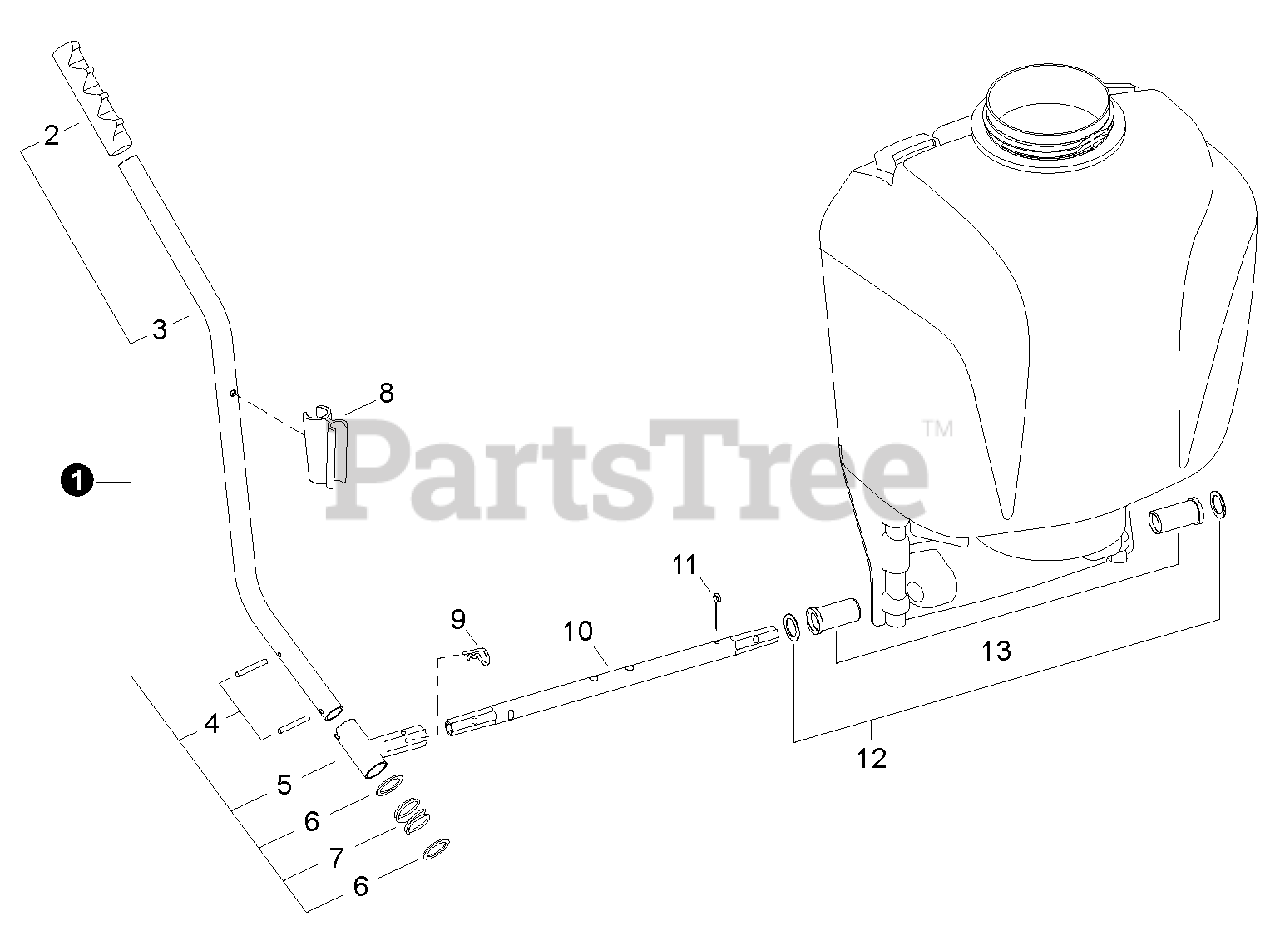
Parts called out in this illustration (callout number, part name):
1	PUMP LEVER KIT
2	GRIP, LEVER
3	LEVER, PUMP
4	PIN, METERING LEVER
5	BRACKET, LEVER
6	WASHER
7	SPRING, METERING LEVER
8	CLIP, WAND
9	PIN, SPLIT
10	SHAFT, PUMP
11	PIN, SHAFT
12	WASHER
13	BUSHING, SHAFT
